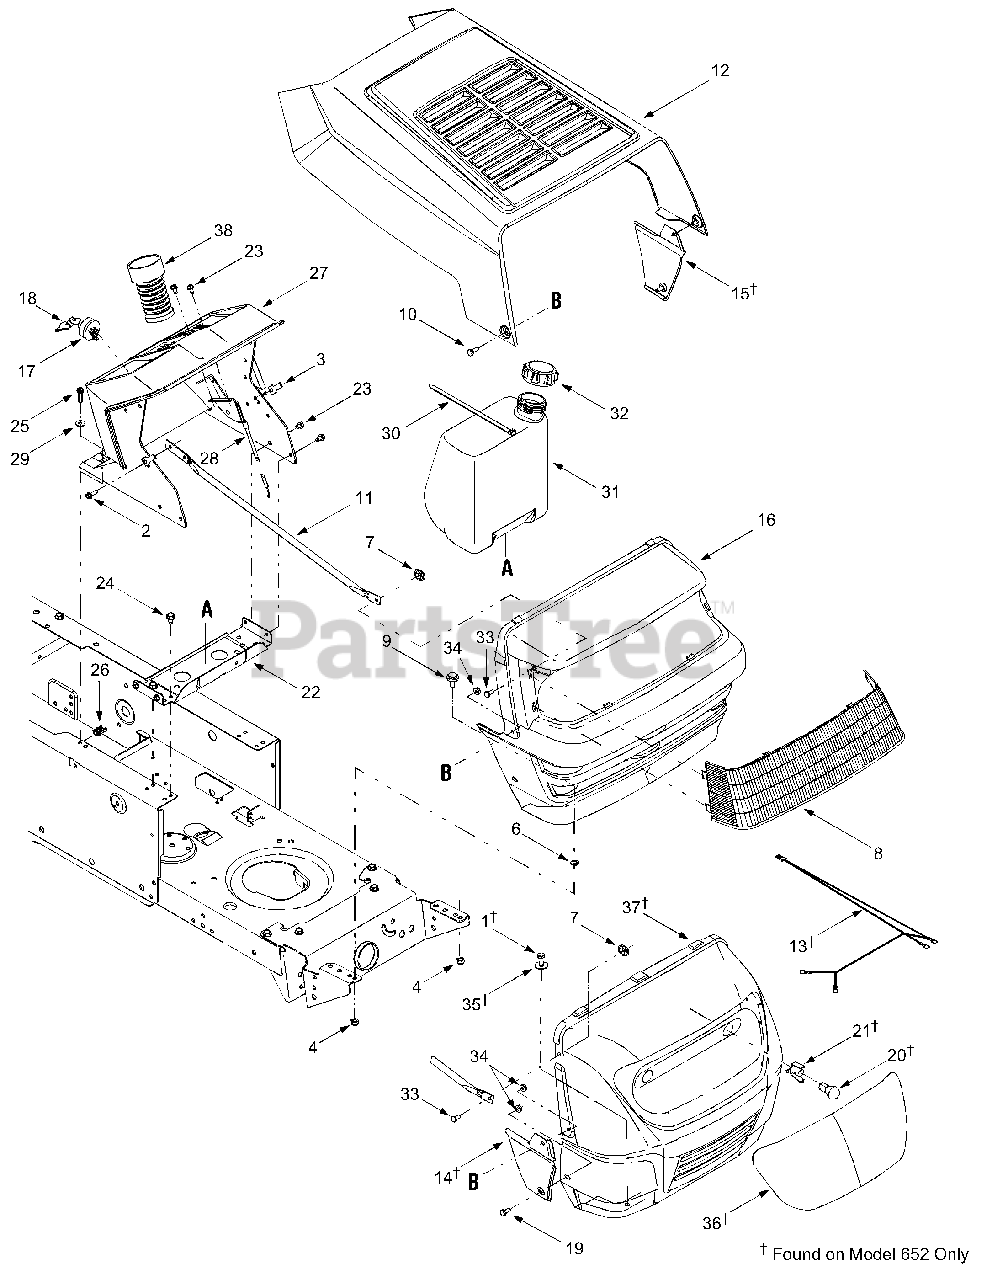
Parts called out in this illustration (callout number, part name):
1	Hex Screw, 5/16-18 x .75
2	Self-tapping Screw, 1/4-20 x .75
3	U-type Speed Nut, 1/4-20
4	Hex Lock Nut, Nylon, 5/16-18
5	Flange Lock Nut, 1/4-20
6	Speed Nut, .3125
7	Push-on Nut, .25
8	Lens, Black
9	Shoulder Screw, 5/16-18 x .625
10	Shoulder Screw, 1/4-20 x .375 /.125
17	Ignition Switch, 6-pin
18	Keys (pair)
19	Hex Screw, 1/4-20 x .620
20	Headlamp, 12V
21	Headlamp Socket
24	Self-tapping Screw, 5/16-18 x .5
25	Self-tapping Screw, 1/4-20 x 1.0
26	U-type Speed Nut, 1/4-20
27	Dash Panel
28	Throttle / Choke Control, 18.5"
29	Flat Washer, .260 x .720 x .060
30	Cable Tie, 30.66
31	Fuel Tank, 1.5 gal.
32	Fuel Tank Cap
33	Rivet, 1/4"
34	Hex Lock Nut, Nylon, 1/4-20
35	Flat Washer, .344 x 1.0 x .063
36	Lens
38	Steering Bellow
